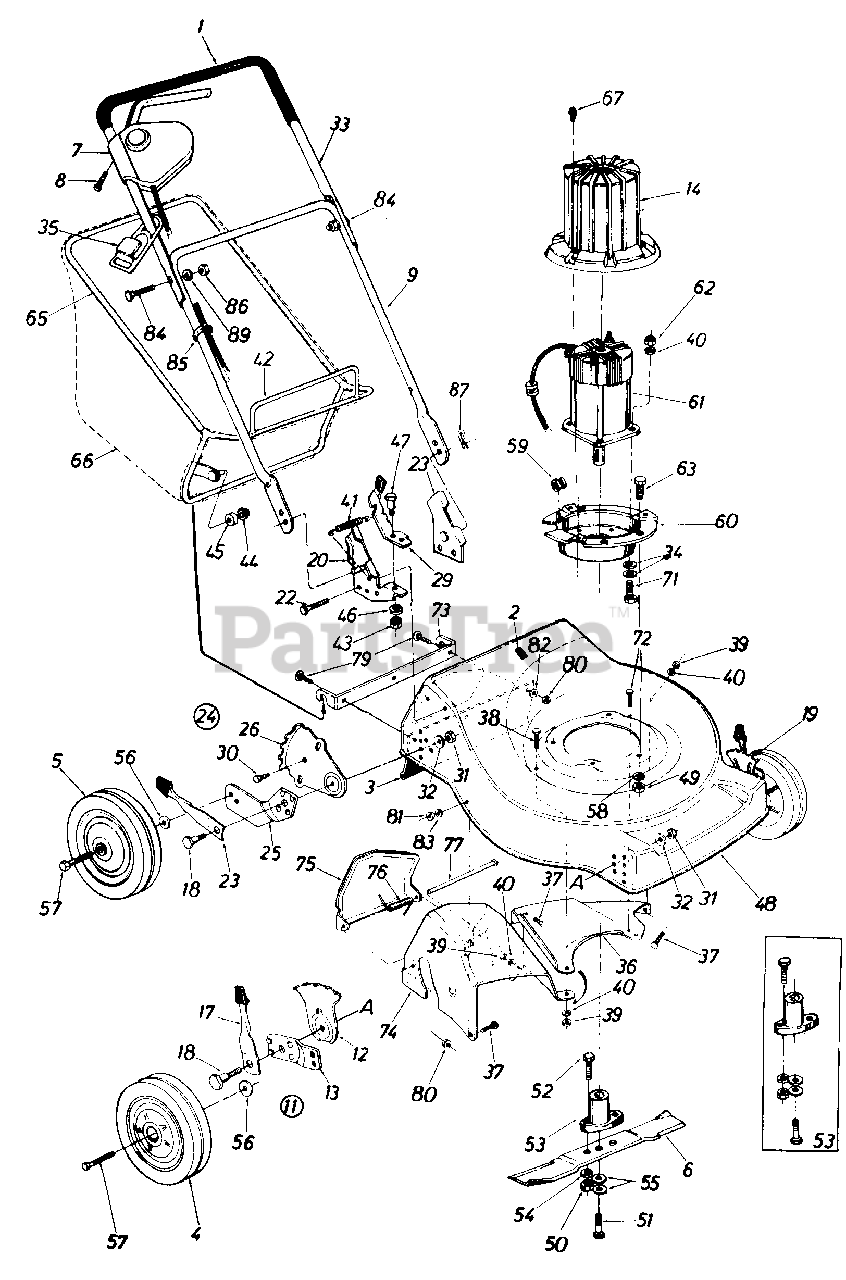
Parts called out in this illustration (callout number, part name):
3	Rear Flap Ass'y.
4	Front Wheel Ass'y. Comp. 7 x 1.75
5	Rear Wheel Ass'y. Comp. 8 x 1 .75
6	20" Blade
7	Control w/Cord
8	Truss Mach. AB-Tap. Scr.
9	Lower Handle
11	Front Height Adj. Ass'y.-R H
12	Front Index Plate
13	Front Pivot Bar
14	Shroud
17	Spring Lever w/Knob
18	Shoulder Bolt .50" Dia. x .375
19	Front Height Adj. Ass'y.-L. H .
20	Handle Brkt. Ass'y.-R.H.
22	Hex Wash. Hd. AB-Tap Scr. 1/4" x.62" Lg.
23	Spring Lever w/Knob
24	Rear Height Adj. Ass'y.-R . H .
25	Rear Pivot Bar-R.H.
26	Rear Index Plate
29	Lock Lever
30	Hex Wash. Tap Scr. '/4 x .62" Lg.
31	Hex Nut 3/8-16 Thd.
32	L-Wash. 3/8" I.D.
33	Upper Handle
34	Fl-Wash. 3/8" I.D. x 1.0" O.D.
35	Restraint
36	Rear Chute Baffle-L.H.
37	Carr. Bolt '/4-20 x .50" Lg.
38	Hex Bolt 1/4-20 x .88" Lg.
39	Hex Nut '/4-20 Thd.*
40	L-Wash. '/4" I.D.
41	Extension Spring
44	Push Cap 3/8" Rod
45	Plastic Roller
46	L-Wash. 5/16" I.D.
47	Shoulder Bolt
50	Hex Nut 5/16-24 Thd.*
51	Hex Bolt 5/16-24 x .75" Lg.
52	Hex Bolt 5/16-24 x 1.00" Lg.
53	Blade Adapter Kit
54	L-Wash. 5/16" I.D.
55	Bell-Wash. .345" I.D. x .88" O.D.
56	Bell-Wash. .400" I.D. x .88" O.D.
57	Shld. Scr. .498" Dia. x 1.45"
58	L-Wash. 3/8" I.D.
59	Cord Restraint
60	Adapter Plate
62	Hex Jam Nut 1/4-20 Thd.
63	Hex Bolt 3/8-16 x 1.00" Lg.
65	Grass Catcher Upper Frame
66	Grass Bag (Without Flip Top)
67	Hex Wash. Hd. F-Tap Scr. #10-32 x .25" Lg.
71	Hex Bolt 1/4-20 x 1.00" Lg.
72	Hex Wash. Hd. Self-Tap Scr. 1/4-20 x .75" Lg.
73	Grass Catcher Hitch Brkt.
74	Rear Chute Baffle-R.H.
75	Chute Door
76	Torsion Spring
77	Hinge Pin .25" Dia. x 7.25" Lg.
79	Carr. Bolt 1/4 -20 x .75" Lg .
80	Hex Sems Nut 1/4-20 Thd.
81	Hex Nut 1/4-20 Thd.
82	Fl-Wash. .281" I.D. x 1.25" O.D.
83	L-Wash. 1/4" I.D.
84	Curved Carr. Bolt 5/16-18 x 1.38" Lg.
85	Cable Tie
86	Hex Nut 5/16-18 Thd.
87	Hairpin Cotter
89	L-Wash. 5/16" I.D.
